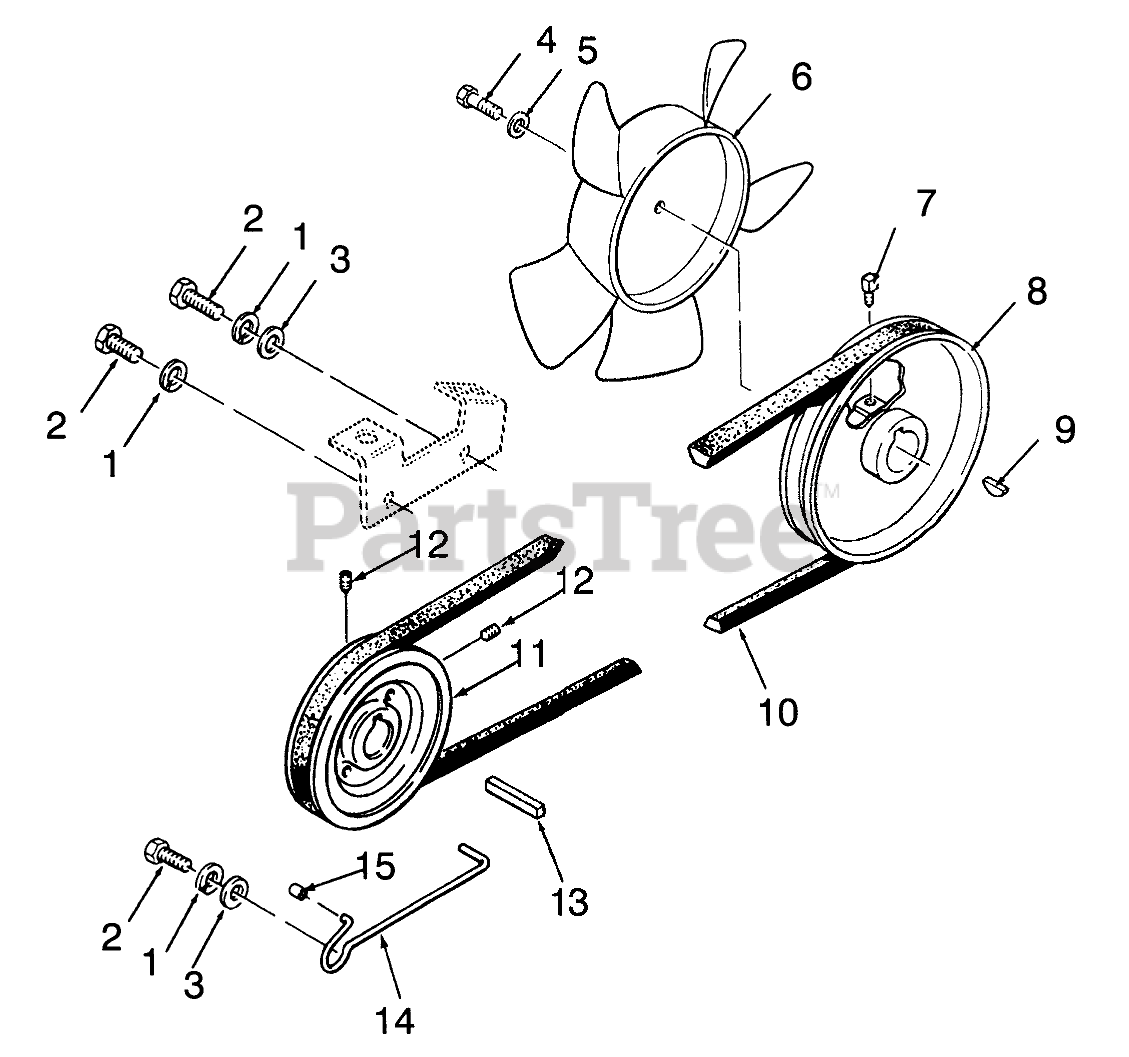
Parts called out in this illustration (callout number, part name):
1	WASHER-LOCK
2	SCREW-HH
3	WASHER-FLAT
4	SCREW-HH
5	WASHER
6	NYLON FAN-L-CW
7	SCREW-SQH
8	PULLEY
9	KEY-HI PRO
10	V-BELT TRANS DRIVE
11	PULLEY
12	SCREW-SET, HSH
14	GUIDE BELT
